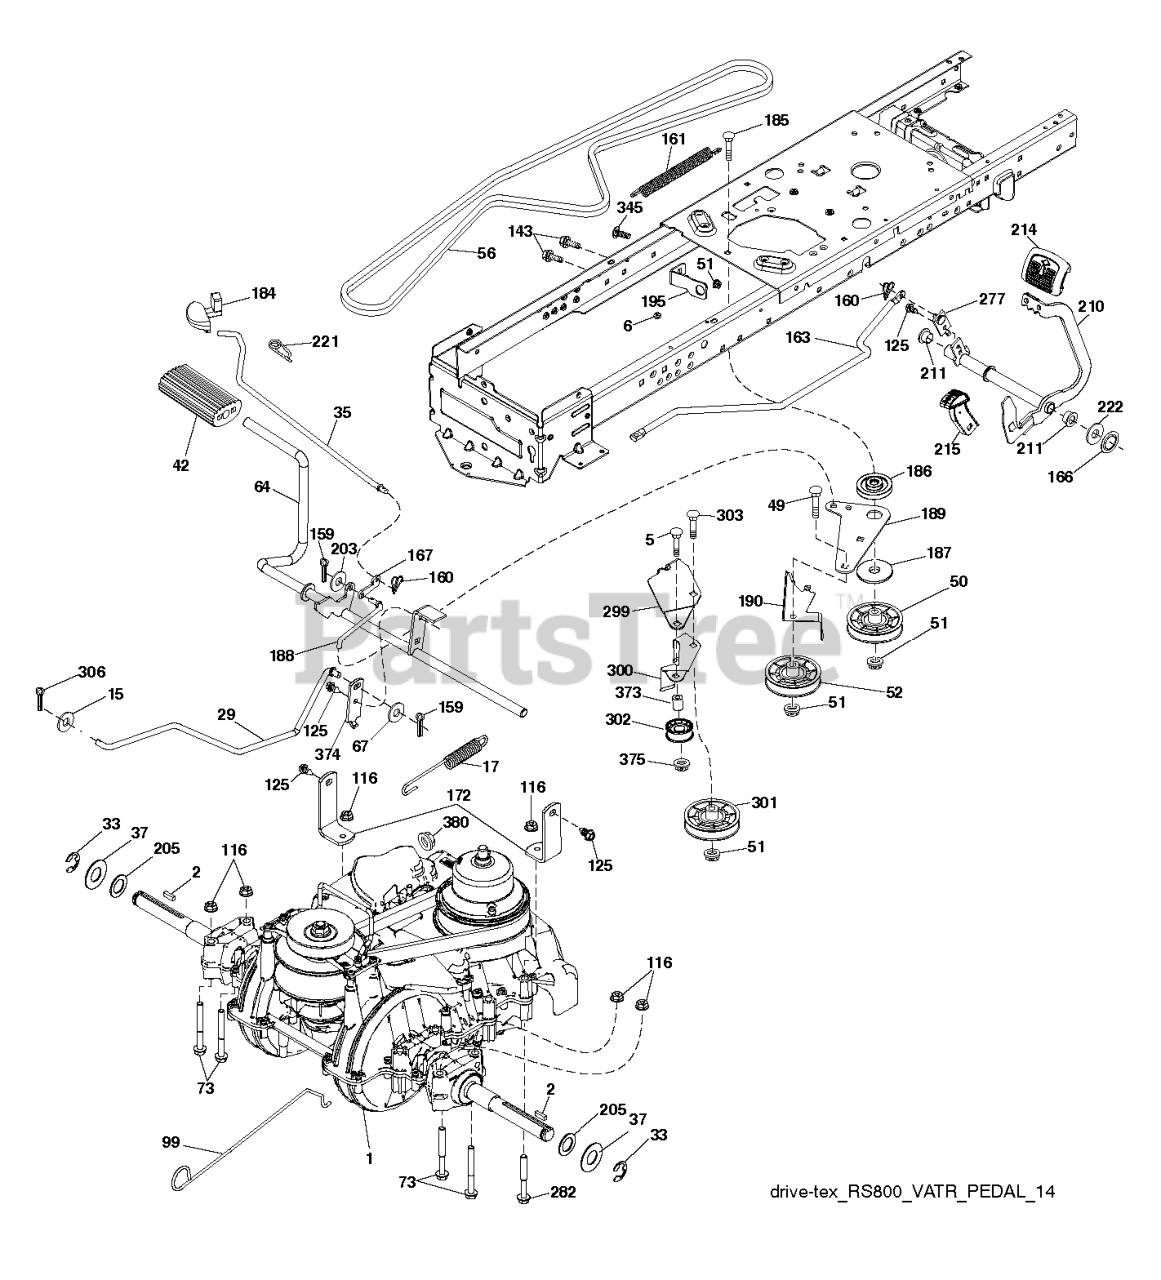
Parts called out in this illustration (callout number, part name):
2	SQUARE KEY
6	BUSHING.SNAP.NYL.BLK.
15	WASHER
17	SPRING.BRAKE.VARIATOR
29	BRAKE.VARIATOR.SD3
35	ROD .BRAKE. PARKING. GT. HUSQ.
37	WASHER.HARDENED
42	PEDAL COVER T
49	BOLT
50	IDLER.FLAT.910.OFFSET
51	NUT LOCK FLG 3/8-16 UNC
52	IDLER.V-GROOVE.910.OFFSET
56	BELT.DRIVE.MOWER.TEX.42"
64	SHAFT VARIATOR PEDAL CROSS
67	WASHER.NYLON;13/32X13/16X.109
73	BOLT HEX 5/16-18 GR 5
99	ROD.BYPASS.VARIATOR.GEN2
116	NUT LOCK HEX FLANGE 5/16-18
125	SCREW
143	Screw 5/16-18 x 1/2 Hex, Self Tapping 5/16-18 x 1/2
159	COTTER PIN
160	RETAINER CLIP
161	SPRING, RETURN LT
163	ROD.CONTROL.PEDAL.VARIATOR
166	NUT.PUSH.625
167	LATCH.BRAKE.SPRING
172	STRAP.TORQUE.VARIATOR
184	HANDLE.PARKING.BRAKE.H (BLK)
186	SPACER.RETAINER
187	WASHER 12/32X2X10GA
188	LINK.CLUTCH.GROUND DRIVE.LONG
189	BELLCRANK.GROUND.DRIVE.TEX.
190	KEEPER.BELLCRANK.DRIVE
195	BRACKET.BRAKE.BRAKE.VAR.SD
203	WASHER
210	PEDAL.ASM.ROCKET.VARIATOR.LT
211	BEARING.NYLON
214	PEDAL.FORWARD.PAD.TEX
215	PEDAL.REVERSE.VARIATOR.MS428
221	RETAINER.SPRING.CLIP.H
222	WASHER 21/32 X 1-1/4 X 10 GA.
277	SUBASM.LINK.ROCKER.PEDAL
282	BOLT HEX FLGHD 5/16-18X3 GR. 5
299	BRACKET.MOUNT.IDLERS
300	KEEPER.IDLERS.REAR.VARIATOR
301	PULLEY.IDLER.V-GROOVE
302	PULLEY.IDLER.FLAT.2"
303	BOLT CARRIAGE
306	PIN COTTER
345	BOLT
373	SPACER.IDLER
374	ARM.CONTROL.BRAKE
375	LOCKNUT
380	NUT.FLG.NYLOCK.1/4-20.GR.G.ZY
